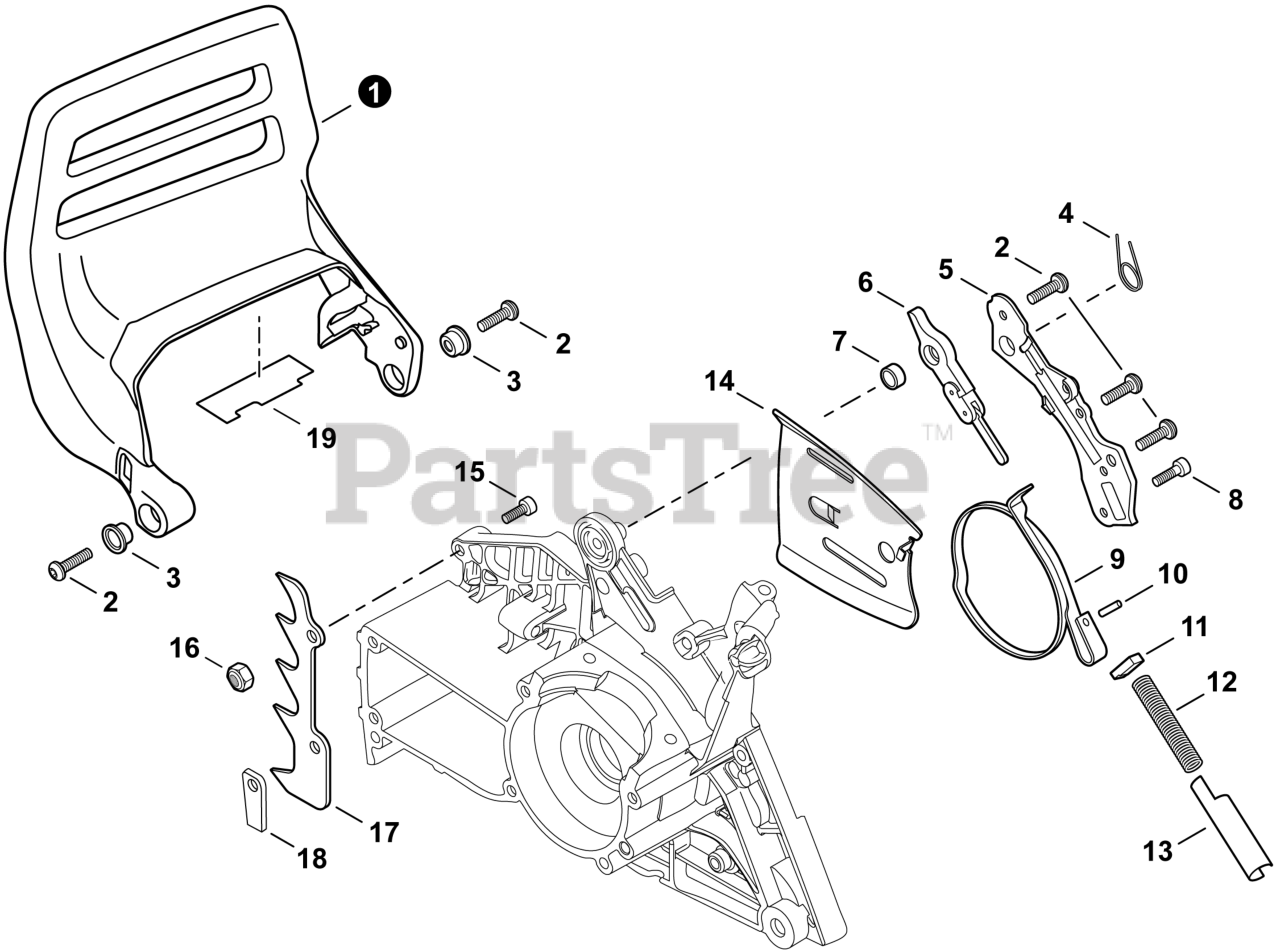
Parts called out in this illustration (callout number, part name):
1	LEVER, BRAKE
2	BOLT, TORX 5x16
3	COLLAR 11.2x16.2xT0.6
4	SPRING, TORSION
5	COVER, BRAKE
6	CONNECTOR, BRAKE
7	SPACER 12x10xT: 1.0
8	BOLT, TORX 4x12
9	BAND, BRAKE
10	PIN, SPRING 3x9.8
12	SPRING, COMPRESSION 12x70.5
13	PLATE, SIDE
14	PLATE, GUIDE - INNER
15	BOLT, TORX 5x16
16	NUT, LOCK M5
17	SPIKE, BUMPER
19	SHIELD, HEAT 75x27x0.15
